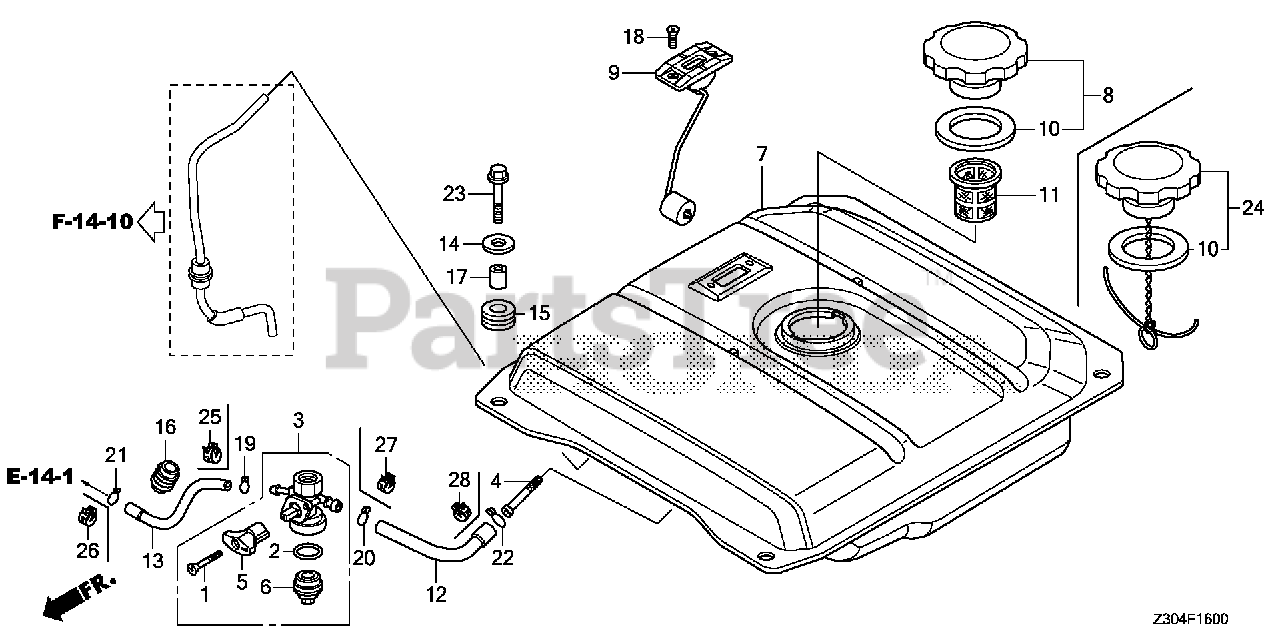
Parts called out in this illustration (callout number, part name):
1	SCREW, OVAL
2	GASKET, FUEL STRAINER CUP
3	PETCOCK ASSY.
4	FILTER, FUEL
5	LEVER, PETCOCK
6	CUP, FUEL STRAINER
7	TANK, FUEL *R280* (POWER RED)
9	METER ASSY., FUEL
10	GASKET, FUEL FILLER CAP
11	FILTER, FUEL
12	TUBE, FUEL TANK (FKM)
12	TUBE, FUEL TANK (FKM) (NOT AVAILABLE)
13	TUBE, FUEL (FKM)
13	TUBE, FUEL (FKM) (NOT AVAILABLE)
14	WASHER (6MM)
15	CUSHION, TANK RUBBER
16	RUBBER, FUEL (9X15X20)
17	COLLAR, TANK CUSHION
18	SCREW, FLAT (5X10)
23	BOLT, FLANGE (6X22)
24	CAP, FUEL FILLER
25	CLIP, TUBE (D8)
26	CLIP, TUBE (D8.5)
27	CLAMP, TUBE (D10)
28	CLAMP, TUBE (D12)
